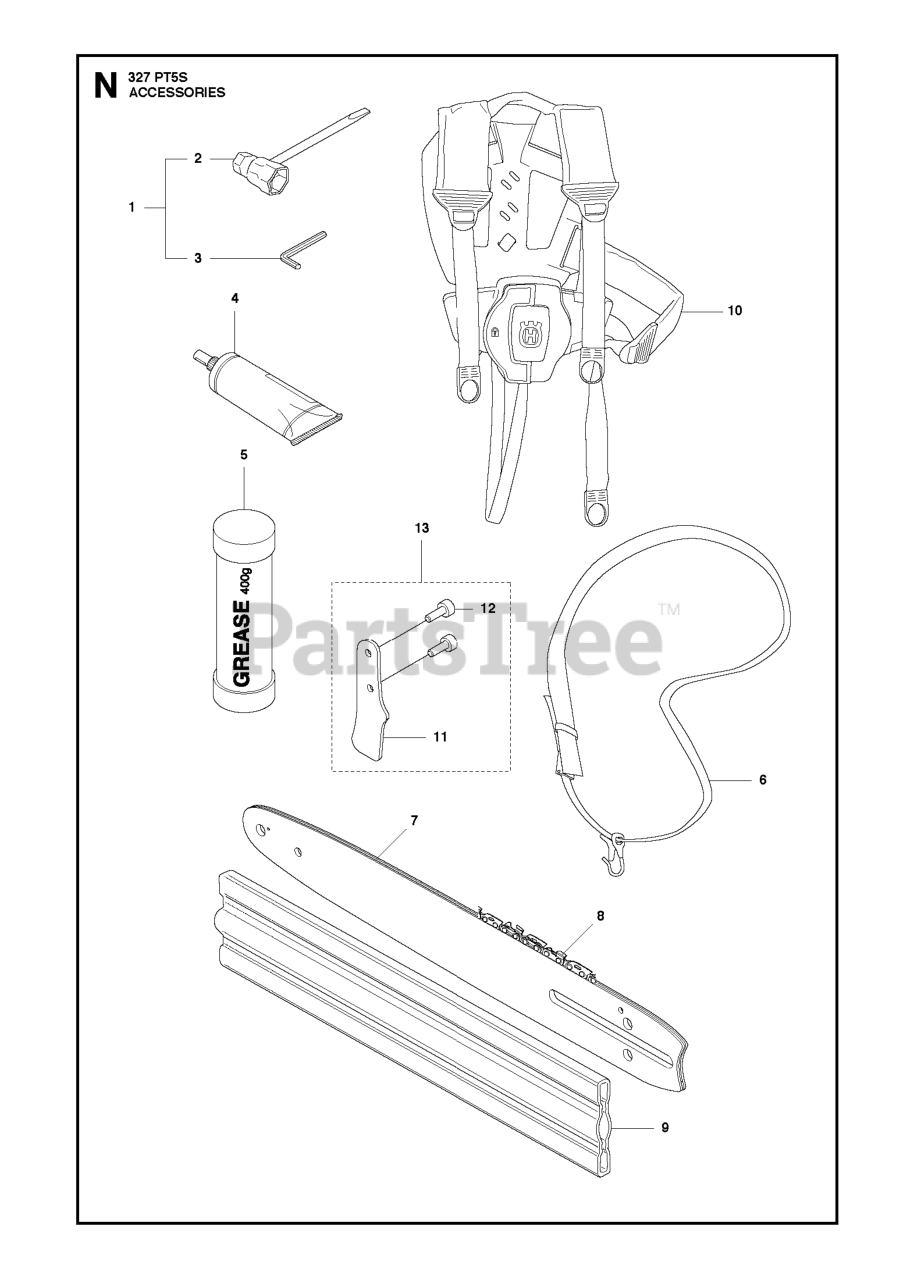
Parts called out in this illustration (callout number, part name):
1	ACCESSORY KIT
2	COMBI TOOL
3	L-KEY WRENCH
5	Grease 400 Grams
6	Harness-w/o warning
6	Harness - Diagonal with sign
7	BAR 1/4" A318 10" 58DL
7	12" DOUBLE GUARD BAR
7	12" BAR, 1/4, .050 A318
8	SAW CHAIN H00 64DL MICRO CHISE
8	SAW CHAIN H00 58DL MICRO CHISE
8	RP12" CHN, H35-44 3/8,.050 MIN
10	RP BALANCE FLEX HARNESS
11	SHEET HOOK
12	SCREW ITXSCM
13	HOOK
